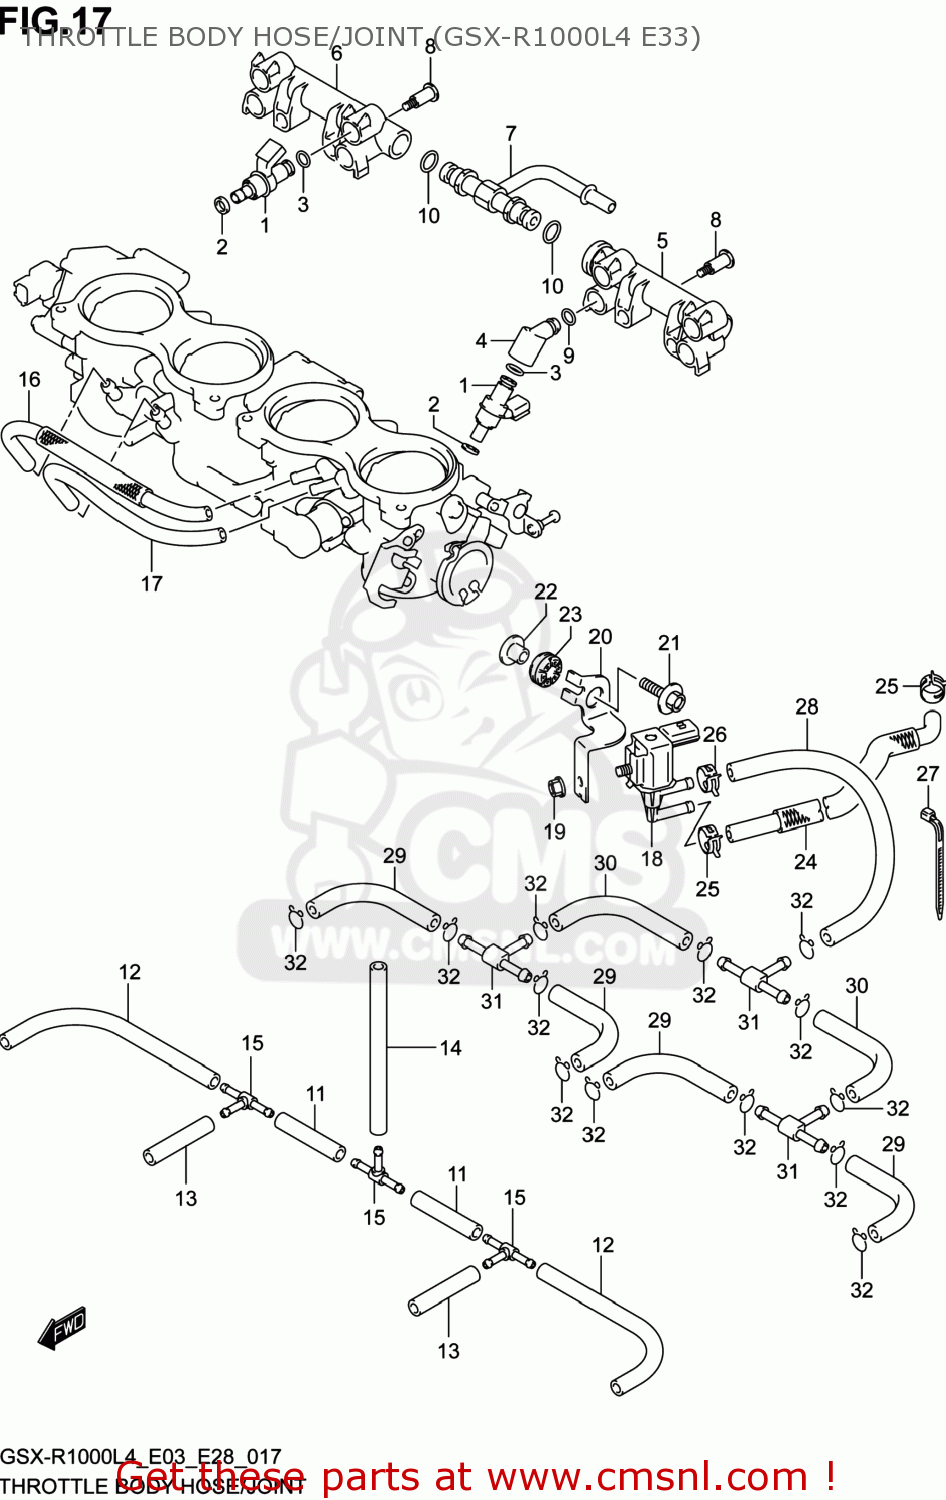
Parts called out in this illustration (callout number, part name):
1	INJECTOR ASSY
2	RING,SEAL
3	O RING
4	PIPE,FUEL
5	PIPE,FUEL
6	PIPE,FUEL
7	JOINT
8	SCREW
9	O RING
10	O RING
11	HOSE
12	HOSE
13	HOSE
14	HOSE
15	JOINT
16	TUBE
17	TUBE
18	VALVE,CANISTER PURGE
19	NUT
20	BRACKET,SOLENOID VALVE
21	BOLT(6X30)
22	SPACER(6.5X10X11.6)
23	CUSHION
24	HOSE,PURGE VALVE
25	CLIP
26	CLIP
27	CLAMP(L:125)
28	HOSE
29	HOSE
30	HOSE
31	JOINT
32	CLIP
